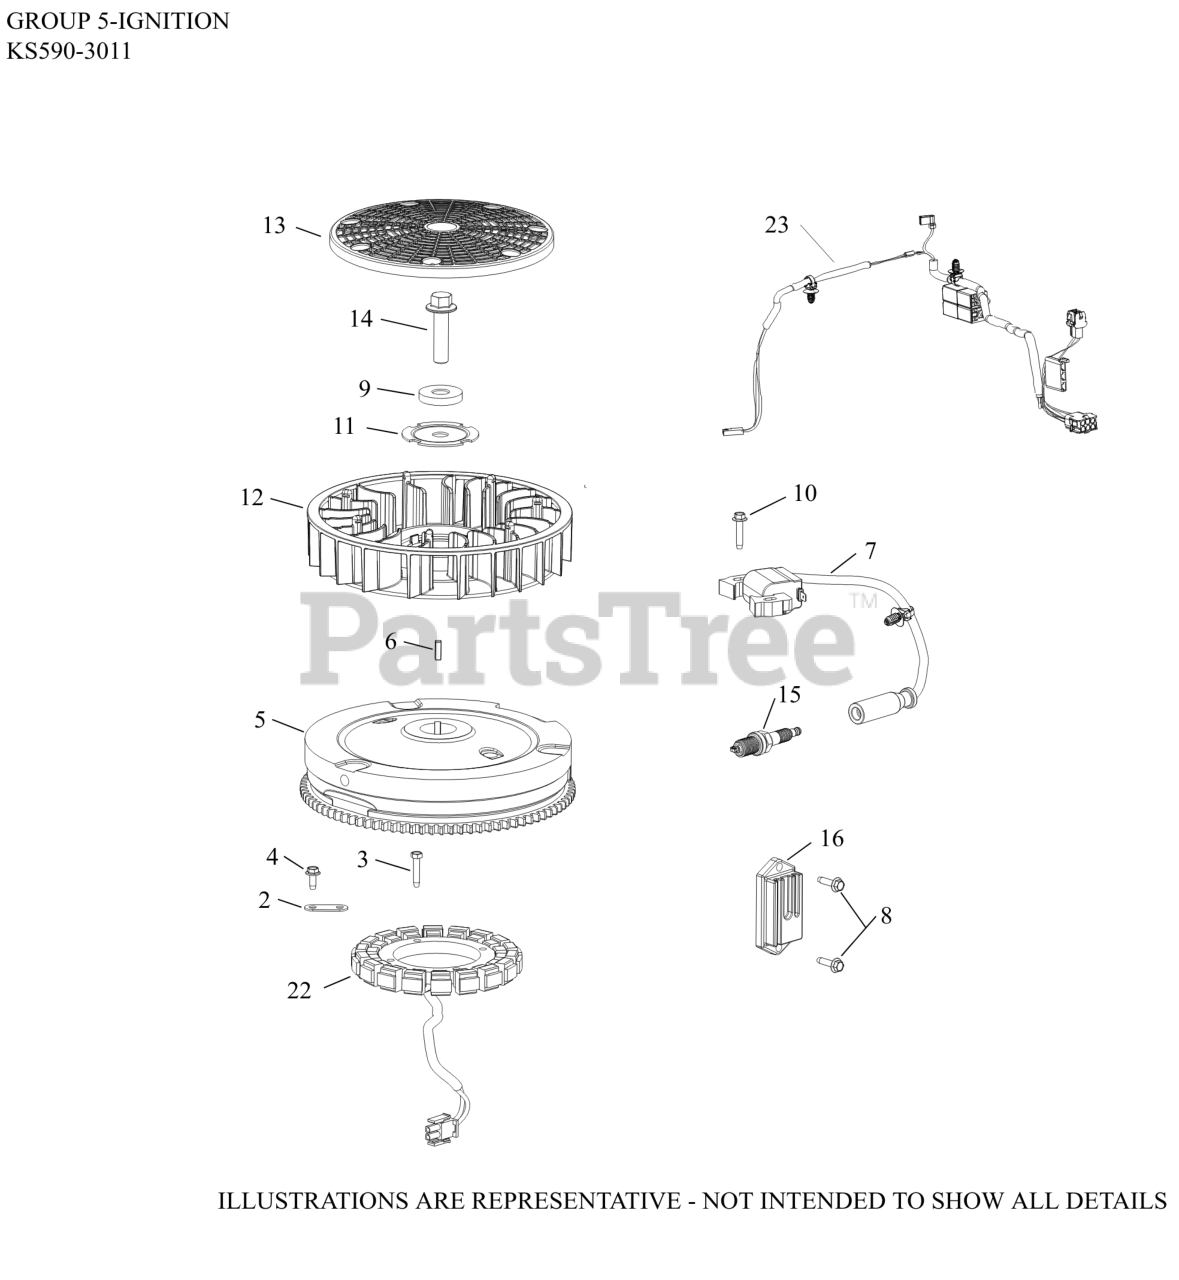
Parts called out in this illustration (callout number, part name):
2	CLIP, STATOR WIRE
3	SCREW, THREAD FORMING
4	SCREW, FLG THD FRM M5X0.8X13
5	FLYWHEEL, ASSY
6	KEY, SQUARE
7	MODULE, INDUCTIVE IGNITION COIL
8	SCREW, THD FRM-USE 25 086 473-S
9	WASHER, FLAT
10	SCREW, THREAD FORMING
11	PLATE, FAN MOUNTING
13	SCREEN, GRASS
14	SCREW, HEX FLANGE
15	PLUG, SPARK
16	REGULATOR/RECTIFIER 12/15A HALF-WAVE STD
22	STATOR ASSEMBLY, 15 AMP
23	HARNESS, WIRING W/COMBO FSO & SB
